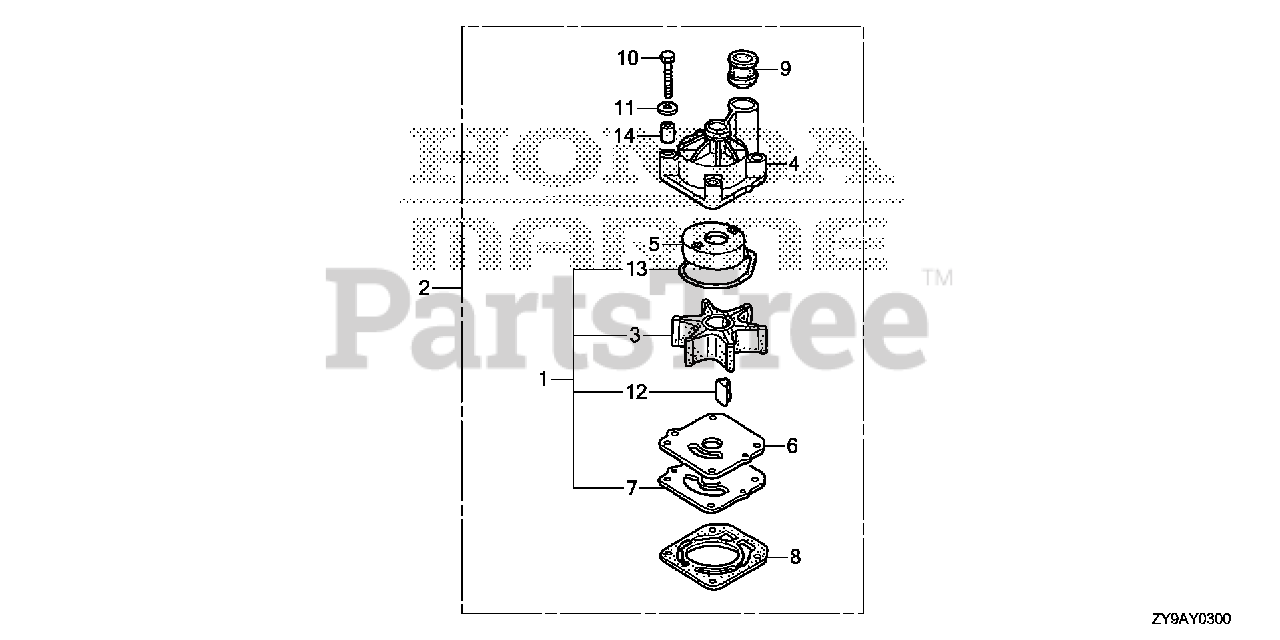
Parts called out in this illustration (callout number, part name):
1	PUMP KIT, IMPELLER
2	PUMP KIT, IMPELLER
3	IMPELLER, PUMP
4	HOUSING, IMPELLER
5	LINER, PUMP
6	COVER, IMPELLER
7	GASKET B, IMPELLER
8	GASKET, WATER PUMP
9	RING, WATER TUBE SEAL
10	BOLT, HEX. (8X55)
11	WASHER (8MM)
12	KEY, WOODRUFF
13	O-RING, WATER PUMP
14	COLLAR, DISTANCE
